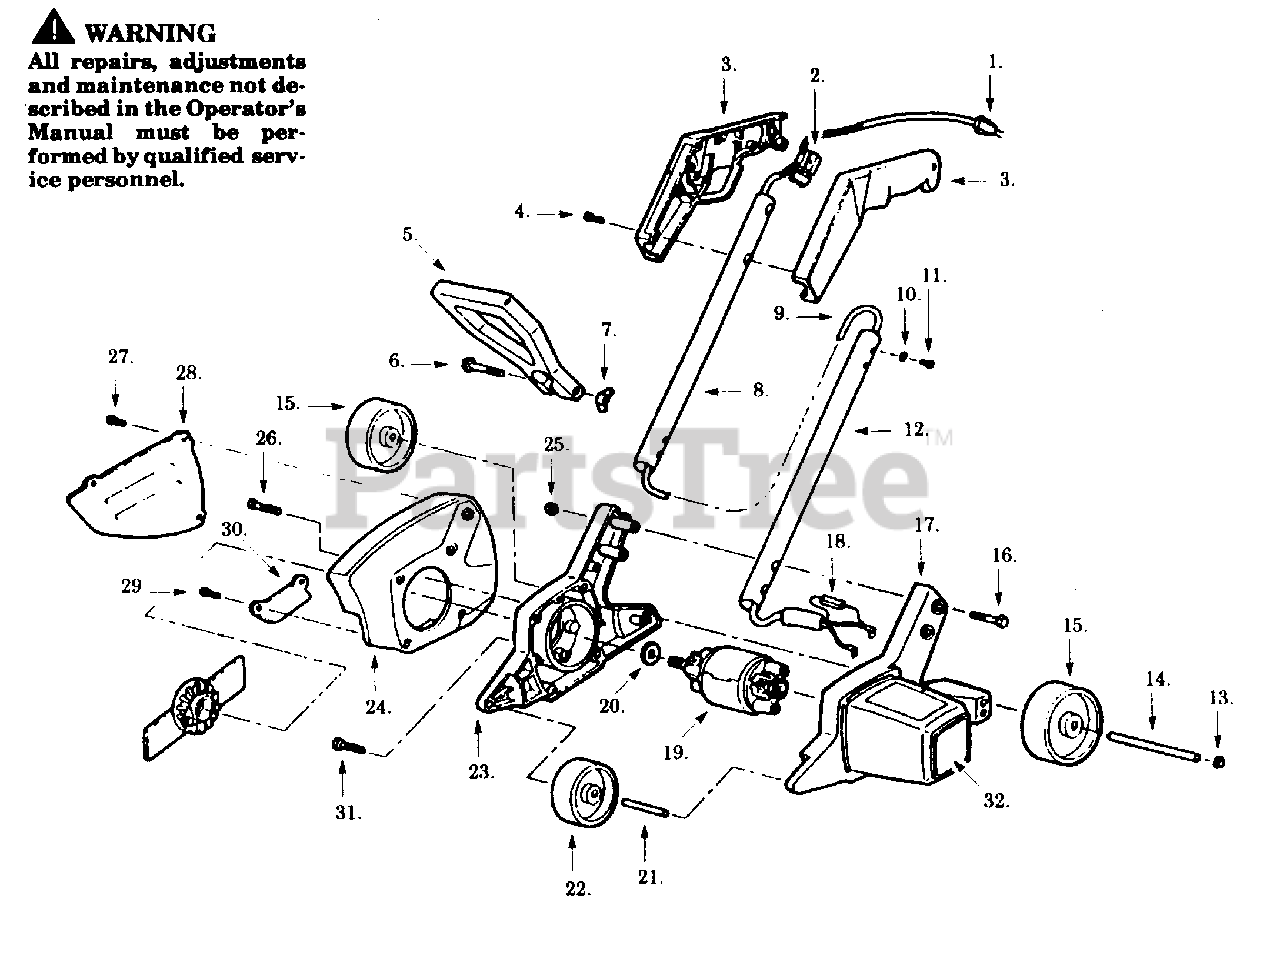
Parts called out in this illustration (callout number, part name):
1	Power Cord
2	Trigger Switch
3	Handle Set
5	Assist Handle
8	Upper Handle Tube
10	Lockwasher
12	Lower Handle Tube
13	Push Nut
17	Motor Cover
18	Rectifier Ass'y.
24	Guard Housing
25	Locknut
28	Side Guard
30	Edge Guide
32	Housing Label
